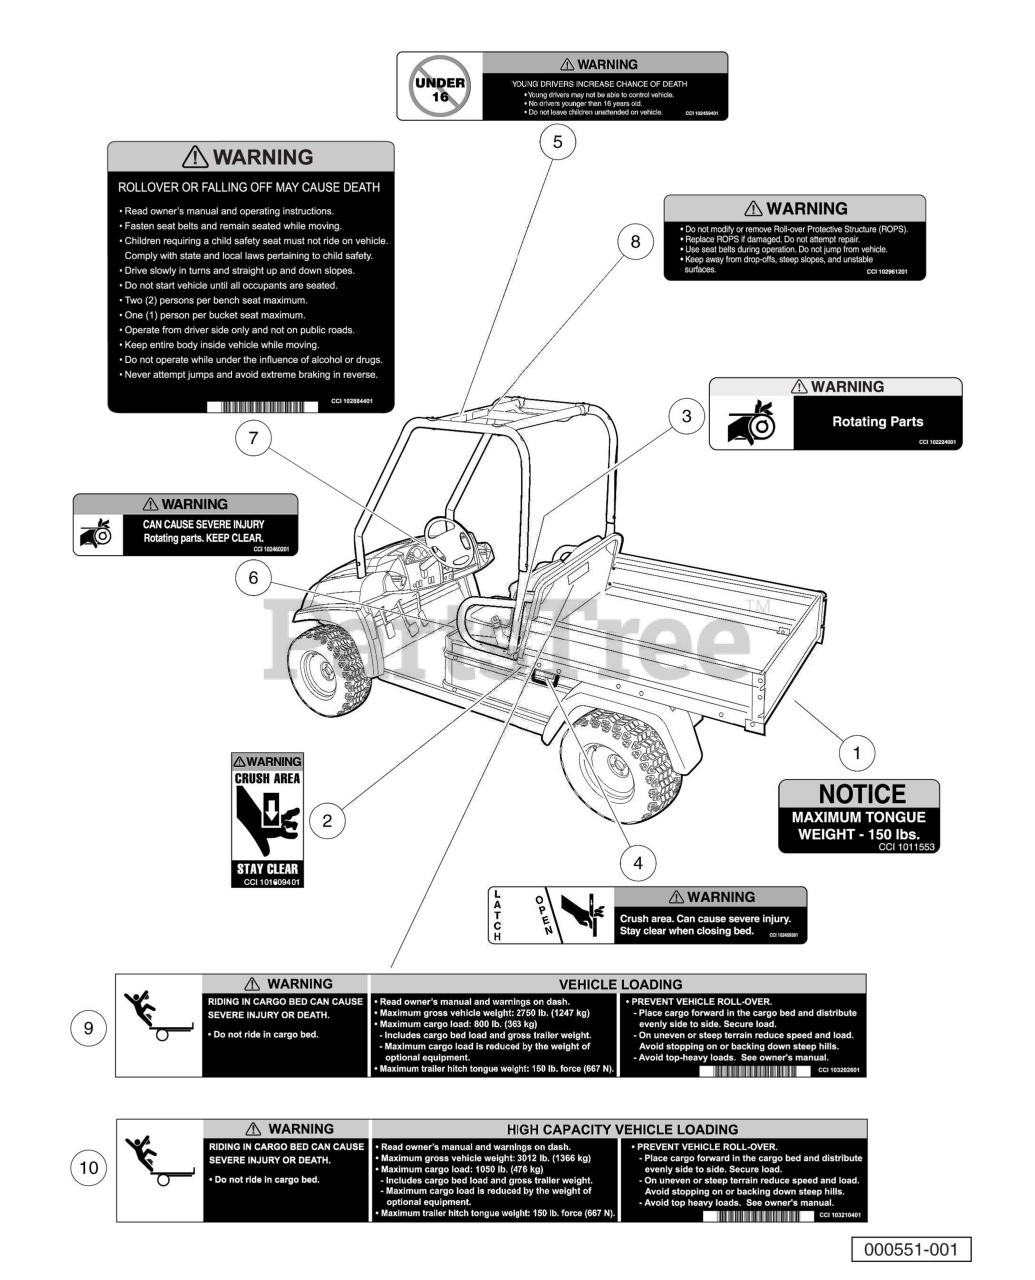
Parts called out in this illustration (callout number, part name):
1	Decal, Trailer Hitch
2	Decal, Crush Area Warning
3	Decal, Rotating Parts Warning
4	Decal, Bed Crush Area Warning
5	Decal, Young Driver Warning
6	Decal, Rotating Parts Warning
7	Decal, Operator Warning
8	Decal, Warning, AWD ROPS
9	Decal, Vehicles Loading, Standard Vehicle
10	Decal, Loading Capacity, High Capacity Option
